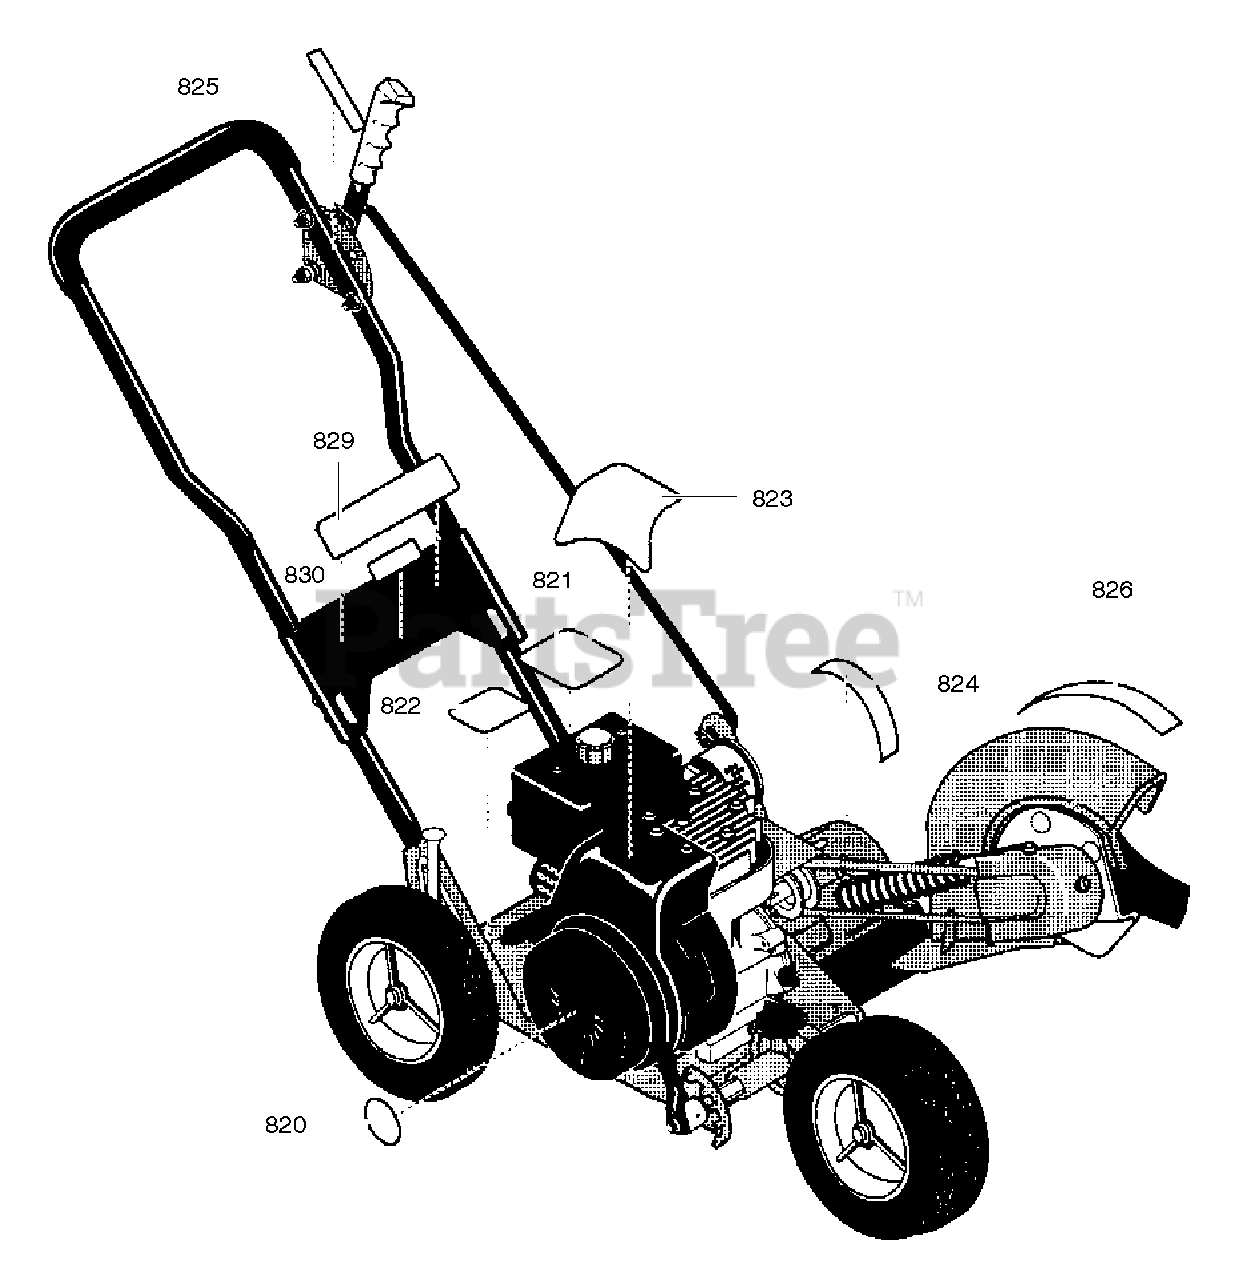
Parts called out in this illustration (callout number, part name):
820	Decal, Recoil Cover
821	Decal, Information Danger
822	Reference Only
823	Decal, Engine
824	Decal, Angle Indicator
825	Decal, Quadrant Selector
826	Decal, Blade Guard
829	Decal, Panel
830	Decal, Husqvarna LE389
